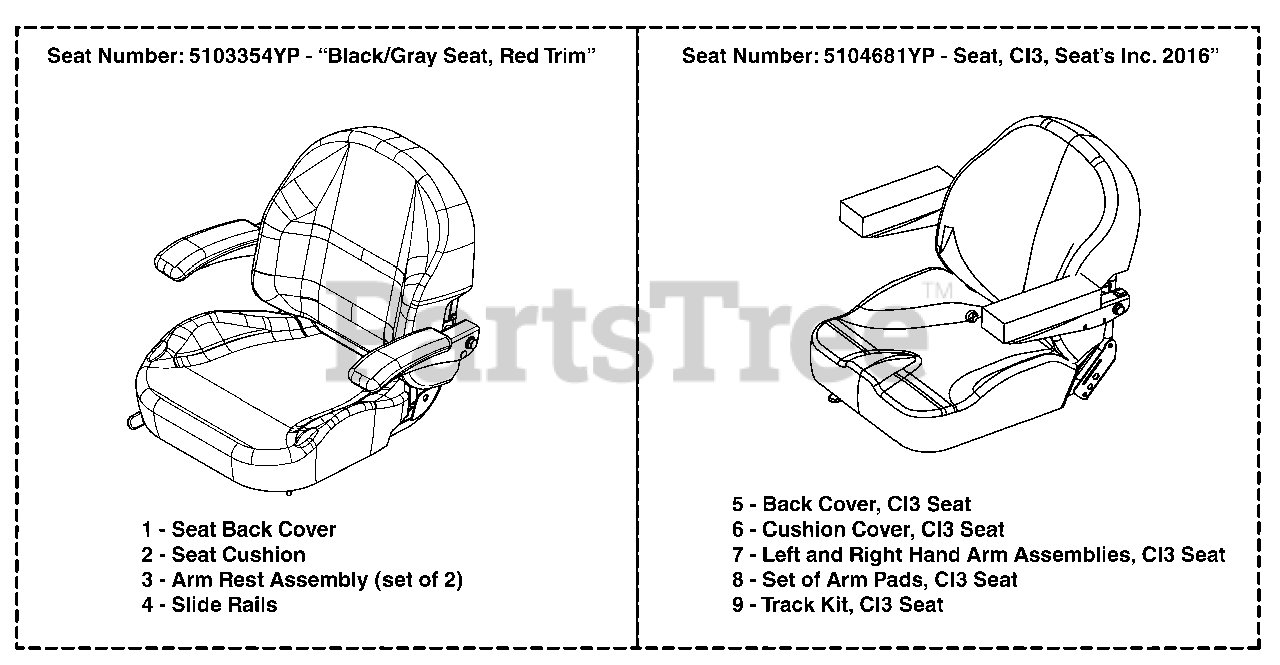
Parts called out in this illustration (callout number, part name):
1	SEAT BACK COVER, SEAT 2012
2	SEAT CUSHION COVER
3	ARM REST, COMPANION
5	BACK COVER, CI3 SEAT
6	CUSHION COVER, CI3 SEAT
7	LEFT AND RIGHT HAND ARM ASSEMBLIES, CI3 SEAT
9	TRACK KIT, CI3 SEAT
